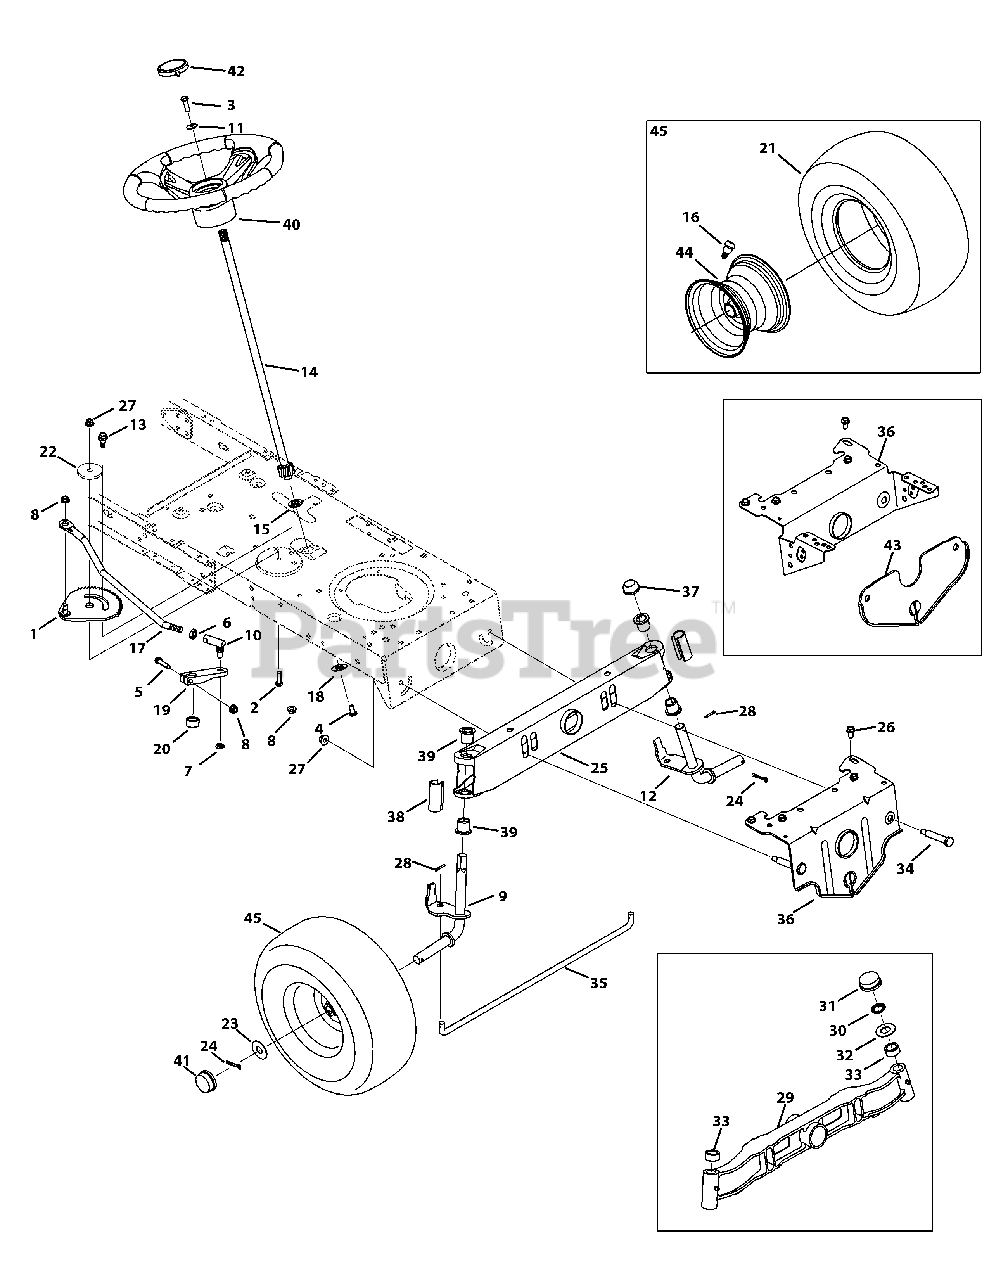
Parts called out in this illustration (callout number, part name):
1	Front Steering Gear Assembly
2	Hex Screw, 3/8-16 x 1.00
3	Hex Screw, 5/16-18 x 1.00, Lock
4	Machine Screw, 5/16-18 x .750
5	Hex Screw, 5/16-18 x 1.75
6	Jam Nut, 7/16-20
7	Jamlock Nut, 3/8-24
8	Flangelock Nut, 5/16-18
9	46" Front RH Axle
10	Ball Joint, 7/16-20
11	Bell Washer, .340 x .872 x .060
12	46" Front LH Axle
13	Shoulder Bolt, 5/16-18 x .435 x .350
14	Steering Shaft, 5/8 x 22.08
15	Flange Bearing, 5/8
16	Valve, tubeless Air
17	Steering Link
18	Cap, 1.25 x .16
19	Steering Block
20	Spacer, .71 x .125 x. 56
22	Shoulder Spacer, .884 x .190
23	Flat Washer,. 781 x 1.590
24	Cotter Pin, 5/32 x 1.25
25	Pivot Axle, Steel
26	Screw, 5/16-18 x .750
27	Flangelock Nut, 3/8-16
28	Cotter Pin, .125 x .75
29	Pivot Axle, Cast Iron
30	Push Nut, 3/4
31	Hub Cap
32	Flat Washer, .78 x 1.59 x .060
33	Spacer, .71 x .125 x .56
34	Shoulder Bolt, 3/8-16 x .500 x 2.38
35	Fixed Rod
36	Pivot Bar Bracket
37	Push Cap, 3/4
38	Standard Axle Cap
39	Flange Bearing, .760 x .941 x 1.0
40	Steering Wheel
41	Hub Cap
42	Cap, Sprig
44	Rim 6.0x4.5
45	Wheel Assembly
